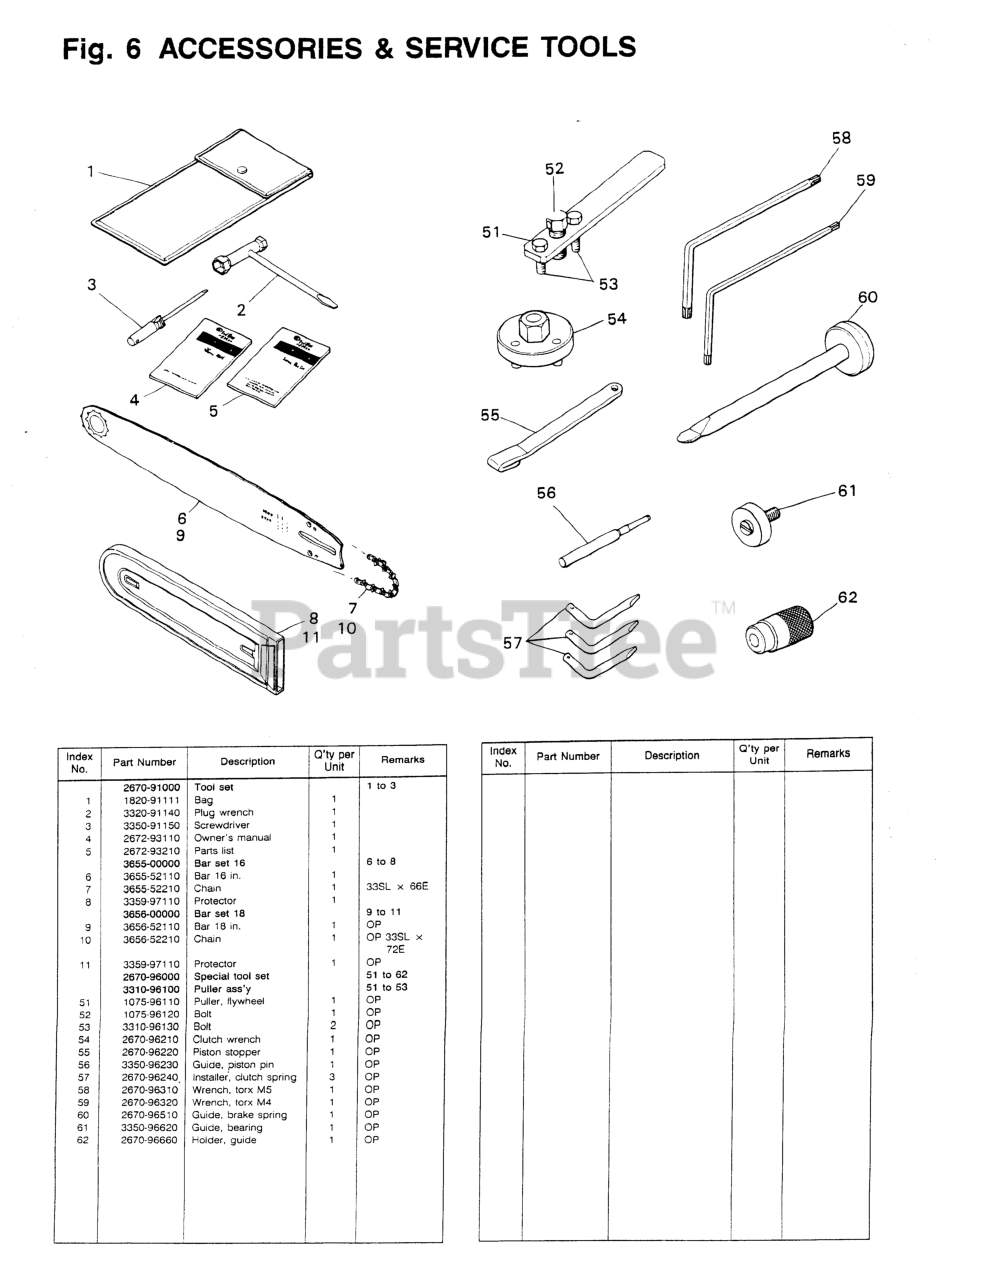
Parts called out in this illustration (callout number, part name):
2	WRENCH, PLUG
5	PARTS LIST
54	WRENCH (TOOL)
55	STOPPER (TOOL)
56	GUIDE (TOOL)
57	WRENCH (TOOL)
58	WRENCH (TOOL)
59	WRENCH (TOOL)
60	GUIDE (TOOL)
61	GUIDE (TOOL)
62	HOLDER (TOOL)
NI	BAR SET 16
NI	BAR SET 18
